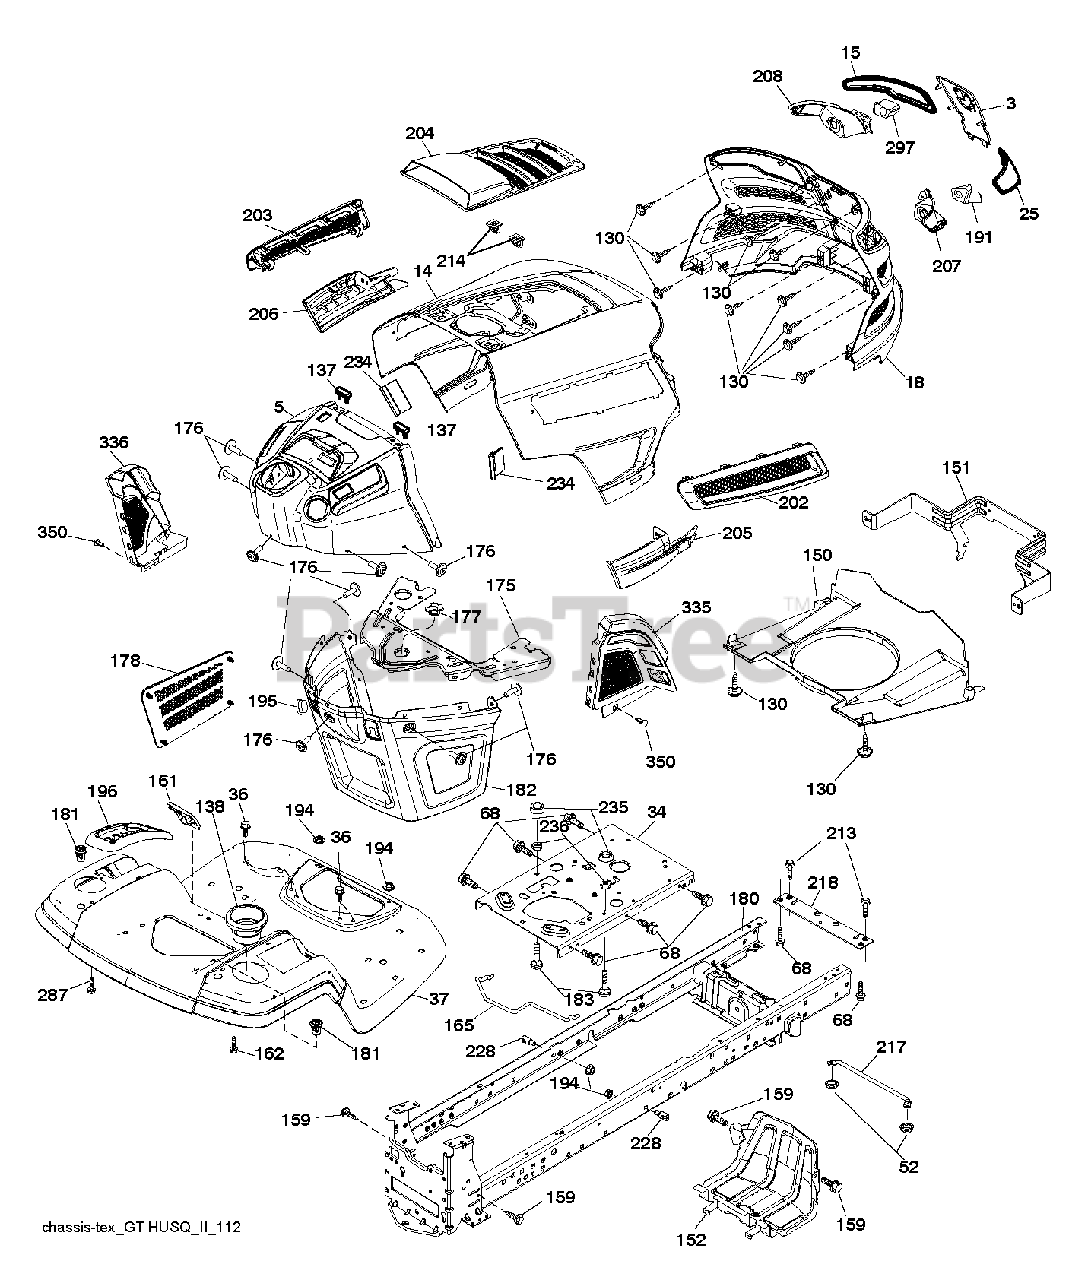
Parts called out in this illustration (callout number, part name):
3	APPLIQUE.SUBASM.GT.HUSQ.II
5	DASH.UPPER.ASSY.GT2.GREY
14	HOOD.ASM.HUSQVARNA.GT.TEX.ORAN
15	LENS.HEADLIGHT.LH.GTII.2011
18	GRILLE.SUBSTRATE.2011.
25	LENS.HEADLIGHT.RH.GTII.2011
34	PLATE.ENGINE.WELDED.CHASSIS
36	SCREW 5/16"
37	FENDER.ERGO.LT.W/CPH.W/FW.ORNG
52	LOCKNUT
68	SCREW LT
130	SCREW.#10 X 0.750.BOS
137	BUMPER DASH
138	HOLDER.CUP.LT.GREY
150	AIR DUCT.GTV2(1.66"RING HEIGHT
151	BRACKET.PIVOT.HOOD.GT.HUSQ.II
152	SHIELD.BROWNING.PNT.GT.V2
159	SCREW, 3/8-16X3/4
161	WINDOW.FUEL.LT.HUSQ.TEX.498
162	SCREW.HI-LO.CONSOLE
165	SUPPORT.TANK.REAR.W/TEX
175	PLATE.CROSSMEMBER.HUSQ
176	SCREW.#10-24X5/8.RN.QU
177	BUSHING, STEERING
178	CARGO.ASM.NET.TXGT.W/C
180	CHASSIS
181	BUSHING.MNT.FEND.CRGO.TEX.49
182	DASH.LOWER.COMMON.12V.ADAPTOR
183	BOLT.5/16-18X1-1/4 FULL THD
191	INSERT.REFLECTIVE.RH.HUSQ.GTII
194	NUT LOCK HEX FLANGE 5/16-18
195	PLUG.HOLE.DASH.LOWER.12V.BLK
196	DECKLFT.CONSOL FULL ASSM GREY
202	VENT.SIDE.RH.GT.HUSQ.II.
203	VENT.SIDE.LH.GT.HUSQ.II.498
204	VENT.TOP.HUSQ.GT2
205	SIDE.TRIM.RH.GT.HUSQ.II
206	SIDE.TRIM.LH.GT.HUSQ.II.GRAY
207	BEZEL LIGHT.RH.GT.II.MYLAR
208	BEZEL LIGHT.LH.GT.II.MYLAR
213	BOLT
214	CLIP.RETAINER.TINNER.
217	ROD.PIVOT.HOOD
218	X-PIECE.HOOD.STOP.NON/
228	STUD.FASTNER.W/ANTI-ROTATE
234	BUMPER.HOOD.TEX.HUSQVARNA
235	SPACER FENDER
236	NUT.CENTERLOCK.5/16-
287	SCREW 1/4X20
297	INSERT.REFLECTIVE.LH.HUSQ.GTII
335	COVER.LOWER.DASH.RH.BLACK
336	COVER-LH.LOWER.DASH.GT2.BLACK
350	CLIP.X-MAS.TREE
